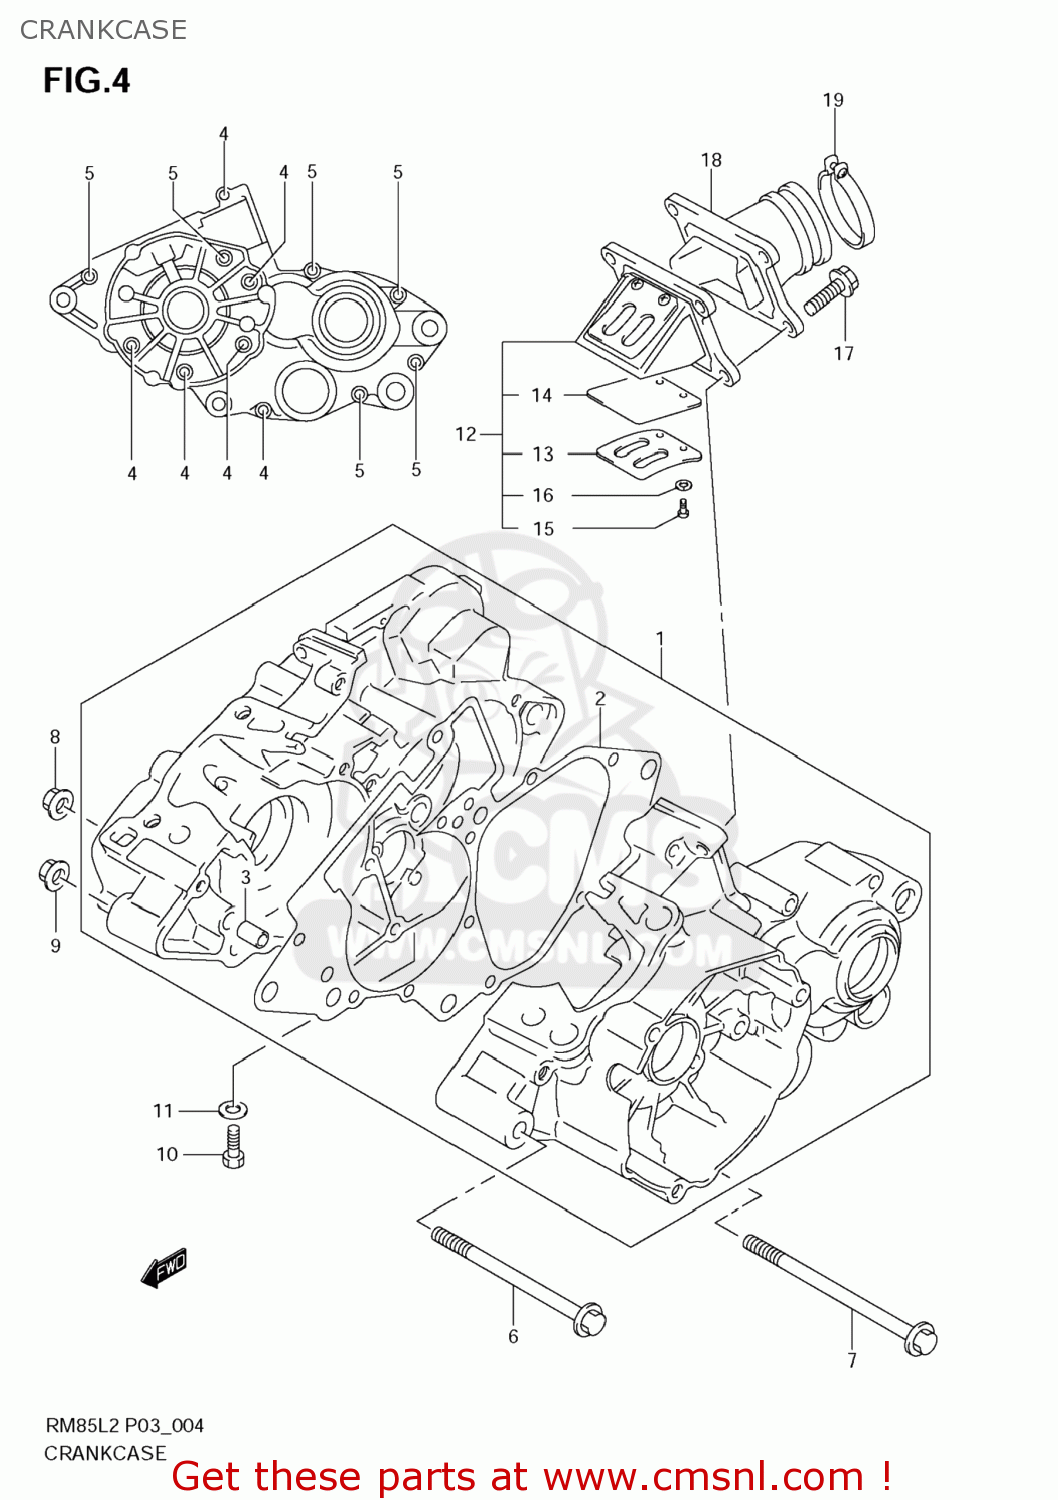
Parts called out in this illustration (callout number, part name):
1	CRANKCASE SET
2	GASKET,CRANKCASE (NAS)
3	PIN
4	BOLT
5	BOLT(6X50)
6	BOLT(10X95)
7	BOLT(8X102)
8	NUT
9	NUT
10	BOLT
11	GASKET(8.2X14X1) (NAS)
12	VALVE ASSY,REED
13	STOPPER,REED VALVE
14	VALVE,REED
15	SCREW
16	WASHER,LOCK
17	BOLT
18	PIPE,INTAKE
19	CLAMP
